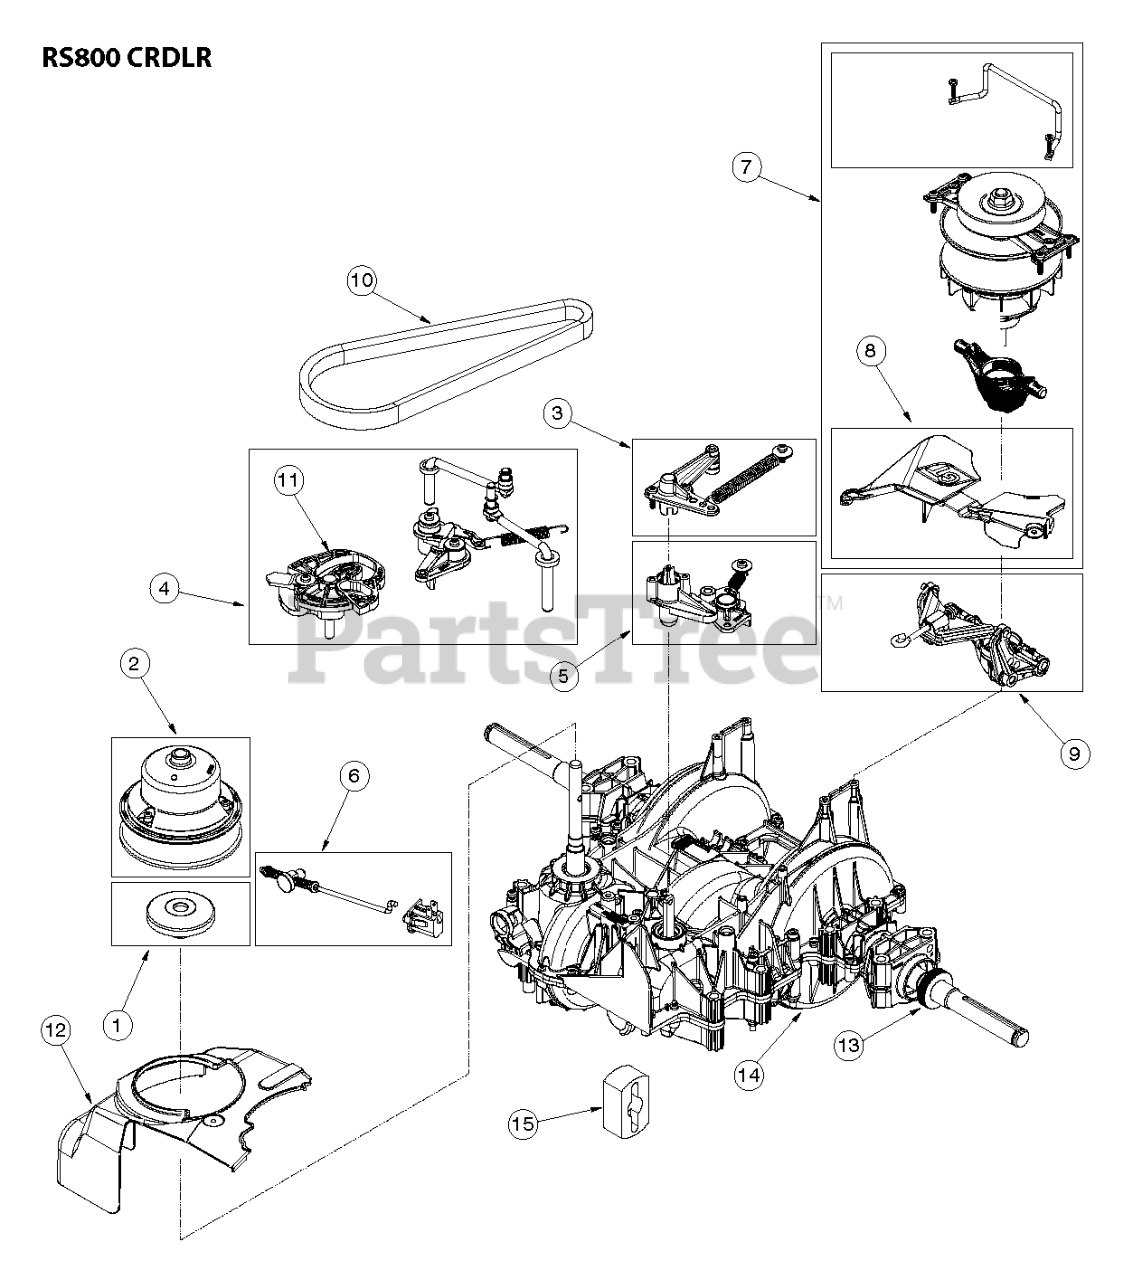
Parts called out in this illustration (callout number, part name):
1	INVERSION SECURITY SYSTEM
2	DRIVEN KIT RS800
3	Husqvarna TBD
4	CONTROL KIT RS800 P
5	BYPASS KIT
6	INVERSION KIT
7	SERVICE.DRIVER.KIT
8	SERVICE.SECONDARY.COVER.RS800
9	VARIATION KIT RS800 PEDAL MY17
10	VARIATION BELT TXL
11	CONTROL CAM RS800 P
12	COVER RS800 P
13	KIT.OUTPUT SEALS.RS800.41857
14	TRANSAXLE.VARIATR.FAST.PDL.CRD
15	DRIVEN TOOL RS800
